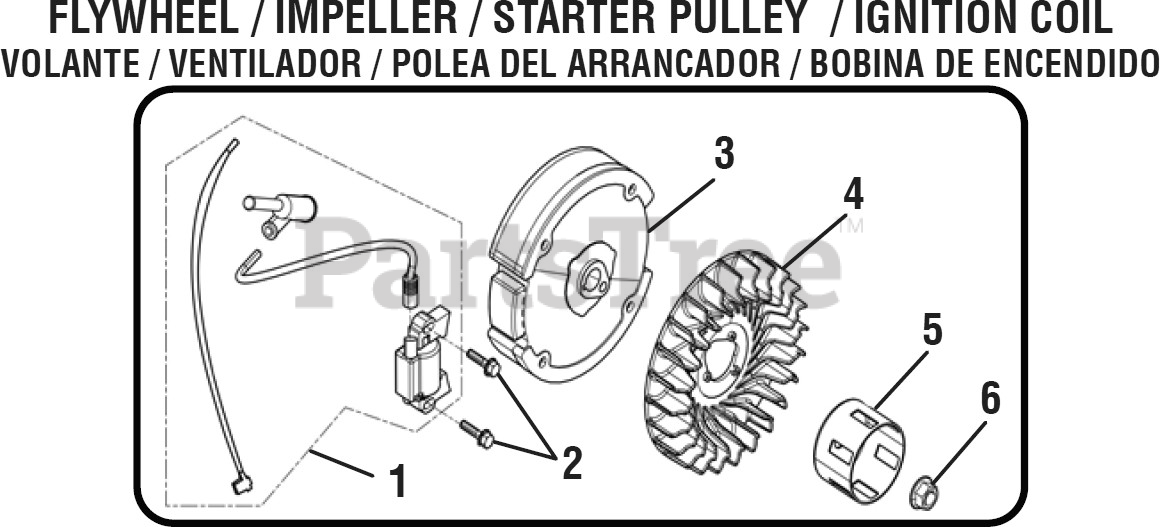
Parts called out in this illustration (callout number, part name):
1	Ignition Coil
3	Flywheel Assembly
4	Impeller
5	Starter Pulley
6	Flywheel Nut
